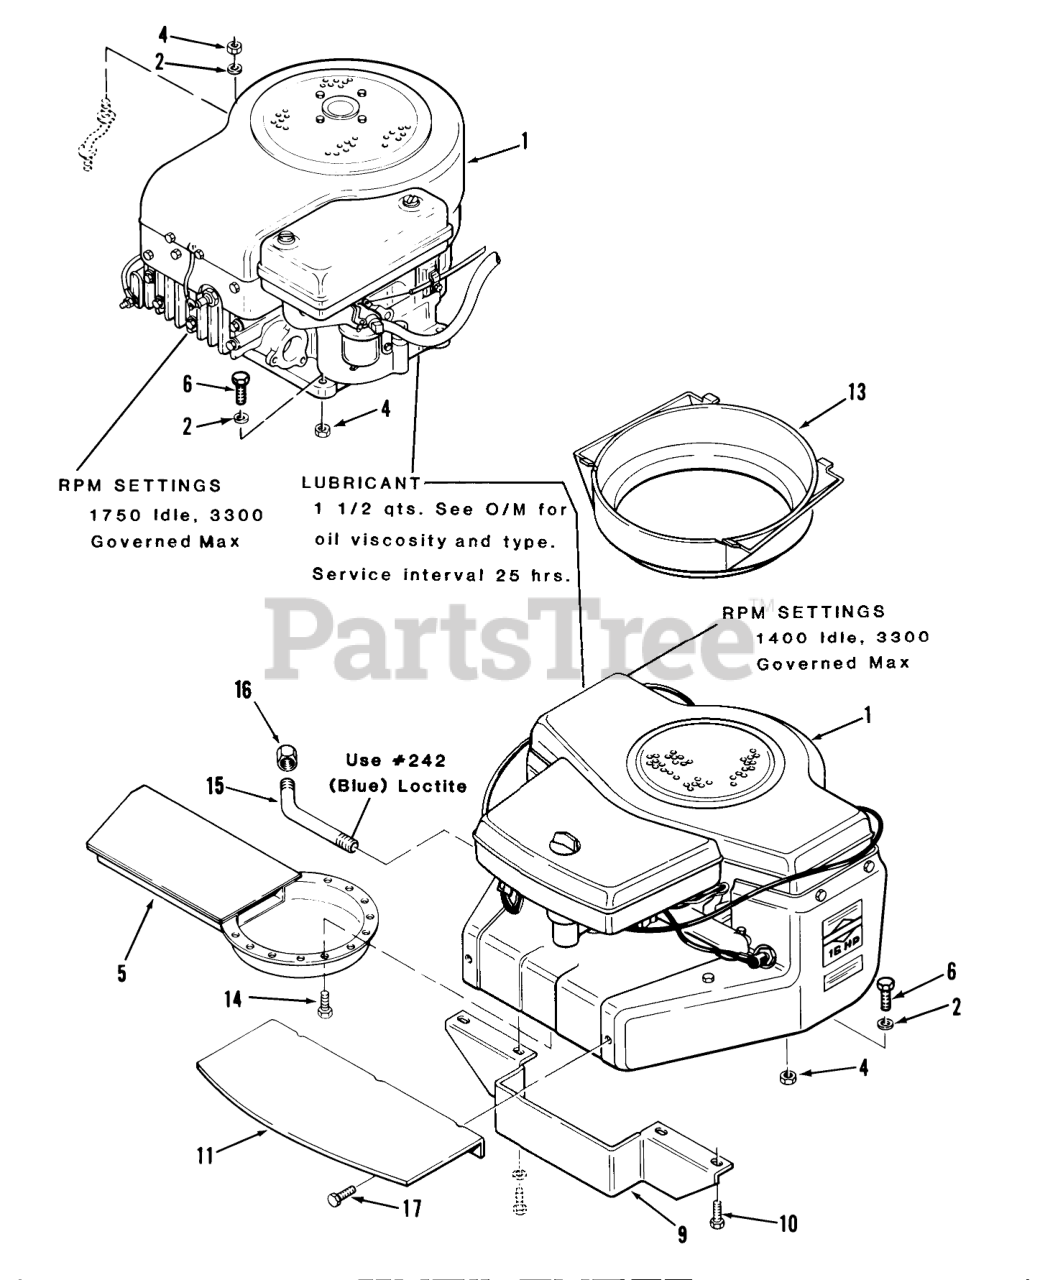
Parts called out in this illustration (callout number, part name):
1	Engine-11HP-BS Model 252707, Type 0222-02
1	Engine-11HP-BS Model 253707, Type 0158-01 211-5 Only
1	Engine-16HP-BS Model 402707, Type 0130-05 216-5 Only
2	WASHER 5/16 SAE
13	DUCT-AIR INTAKE
